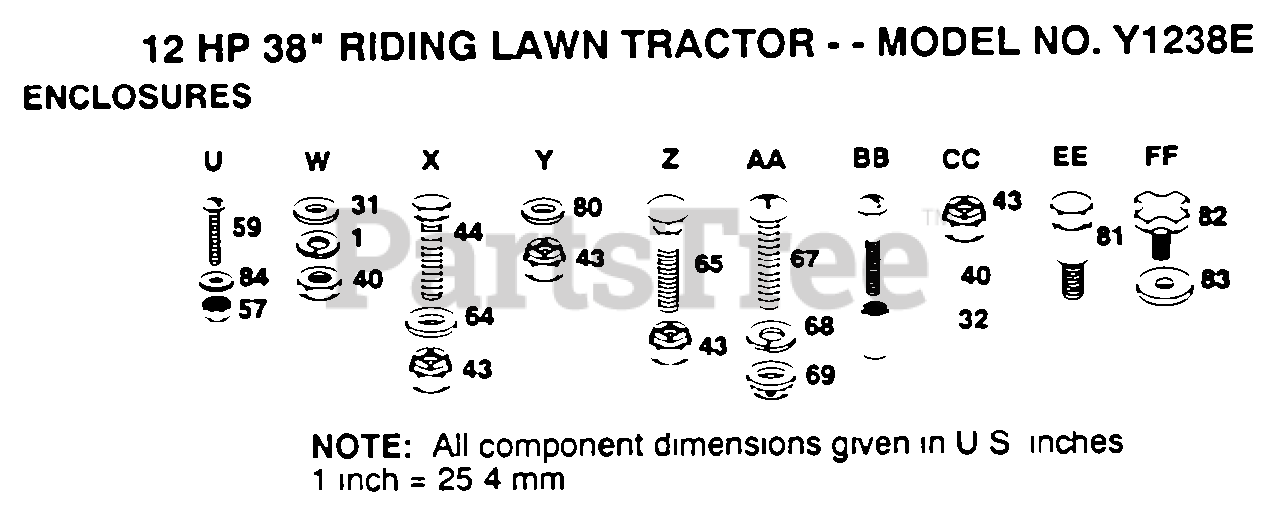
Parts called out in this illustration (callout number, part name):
1	LOCKWASHER
31	WASHER PM
32	BELT GUIDE
44	BOLT
59	SCREW
64	WASHER
65	BOLT
67	SCREW
68	LOCKWASHER
69	WELDNUT
80	WASHER
81	"BOLT,SHOULDER"
82	"KNOB 1/2"" YT"
83	WASHER
84	WASHER
